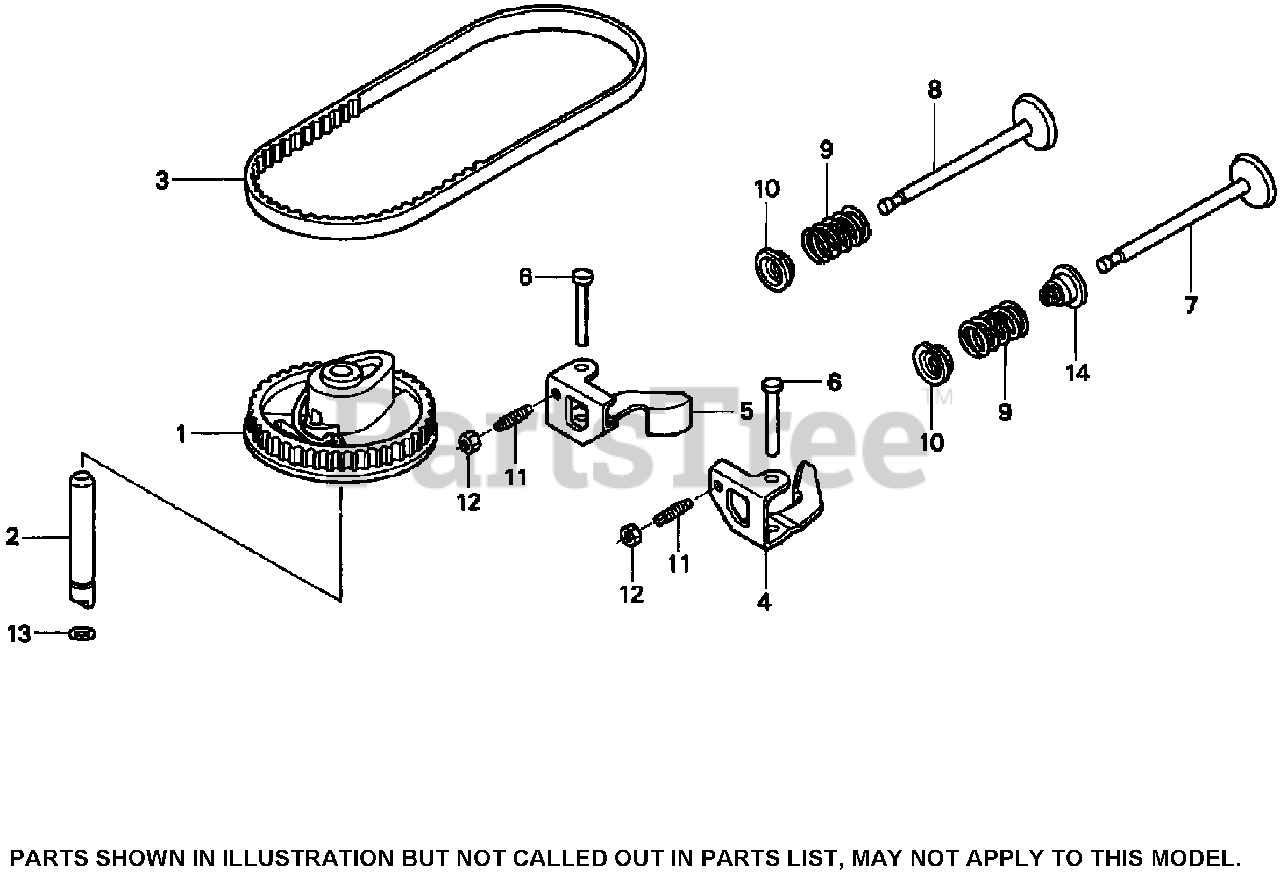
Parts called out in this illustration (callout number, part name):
1	PULLEY-CAMSHAFT
2	SHAFT-PULLEY
3	BELT-TIMING (84HU7 G-200)
4	ARM-IN. VALVE ROCKER
5	ROCKER ARM-VALVE, EXHAUST
6	SHAFT-ARM, ROCKER
7	VALVE, IN.
8	VALVE-EXHAUST
9	SPRING-VALVE
10	RETAINER-VALVE SPRING
11	SCREW-TAPPET, ADJ.
12	NUT-TAPPET, ADJ.
13	O-RING (6.8X1.9)
14	SEAL-STEM, VALVE
